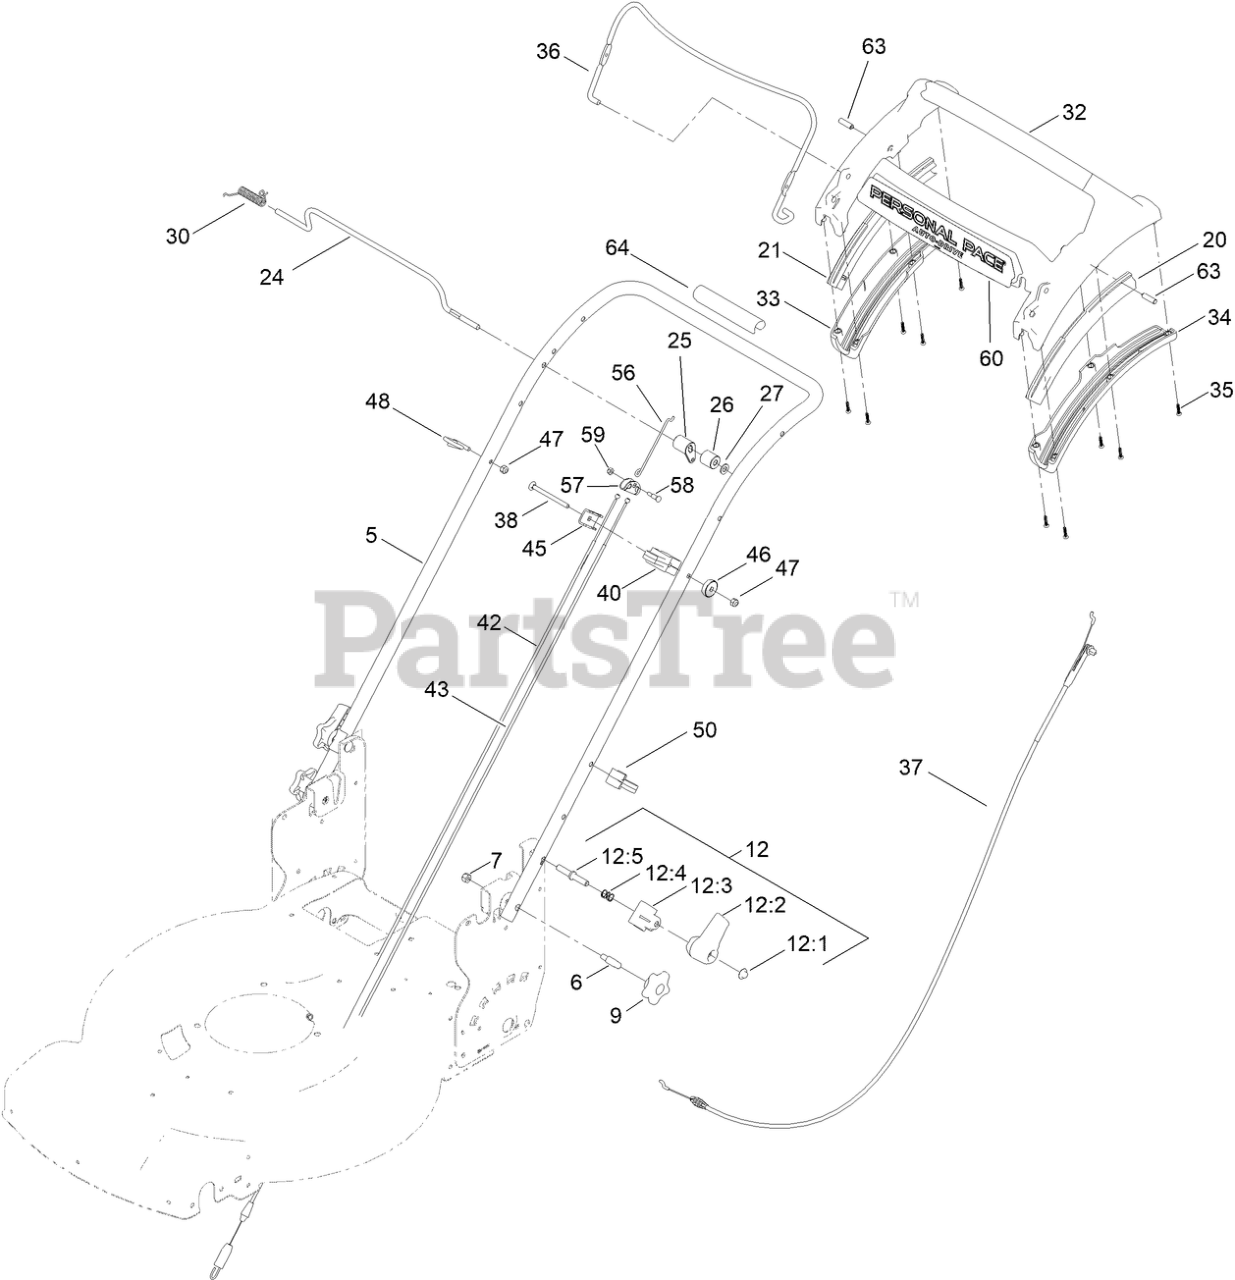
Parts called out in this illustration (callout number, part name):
5	HANDLE-CURVED, AWD
6	BOLT-SHOULDER, HANDLE
7	NUT-HEX
9	KNOB-HANDLE
12	QUICK RELEASE ASM
12:1	NUT-PUSH
12:2	LEVER-RELEASE
12:3	ANCHOR-SPRING
12:4	SPRING-COMPRESSION
12:5	ROD-RELEASE
20	GUIDE-CURVED, LH (RWD)
21	GUIDE-CURVED, RH (RWD)
24	ROD-CONTROL, TRACTION
25	LEVER-TRACTION, AWD
26	SPACER-LEVER, TRACTION
27	WASHER-PLAIN
30	SPRING-TORSION
32	HANDLE-PERSONAL PACE, CURVED
33	BOTTOM-HANDLE, RH
34	BOTTOM-HANDLE, LH
35	SCREW-PPH
36	BAIL-BRAKE
37	CABLE-BRAKE, PP BS
38	SCREW-CARR
40	ANCHOR-CABLE, AWD
42	CABLE-TRACTION, FRONT (AWD)
43	CABLE-TRACTION, REAR (AWD)
45	CLAMP-CABLE
46	WASHER-CURVED
47	NUT-HEX
48	GUIDE-ROPE
50	GUIDE-CABLE
56	LINKAGE-EQUALIZER
57	YOKE-CABLE
58	BOLT-EQUALIZER
59	NUT-HEX
60	DECAL - ADS, HANDLE
63	PIN-HANDLE, PP
64	HANDLE-COVER
